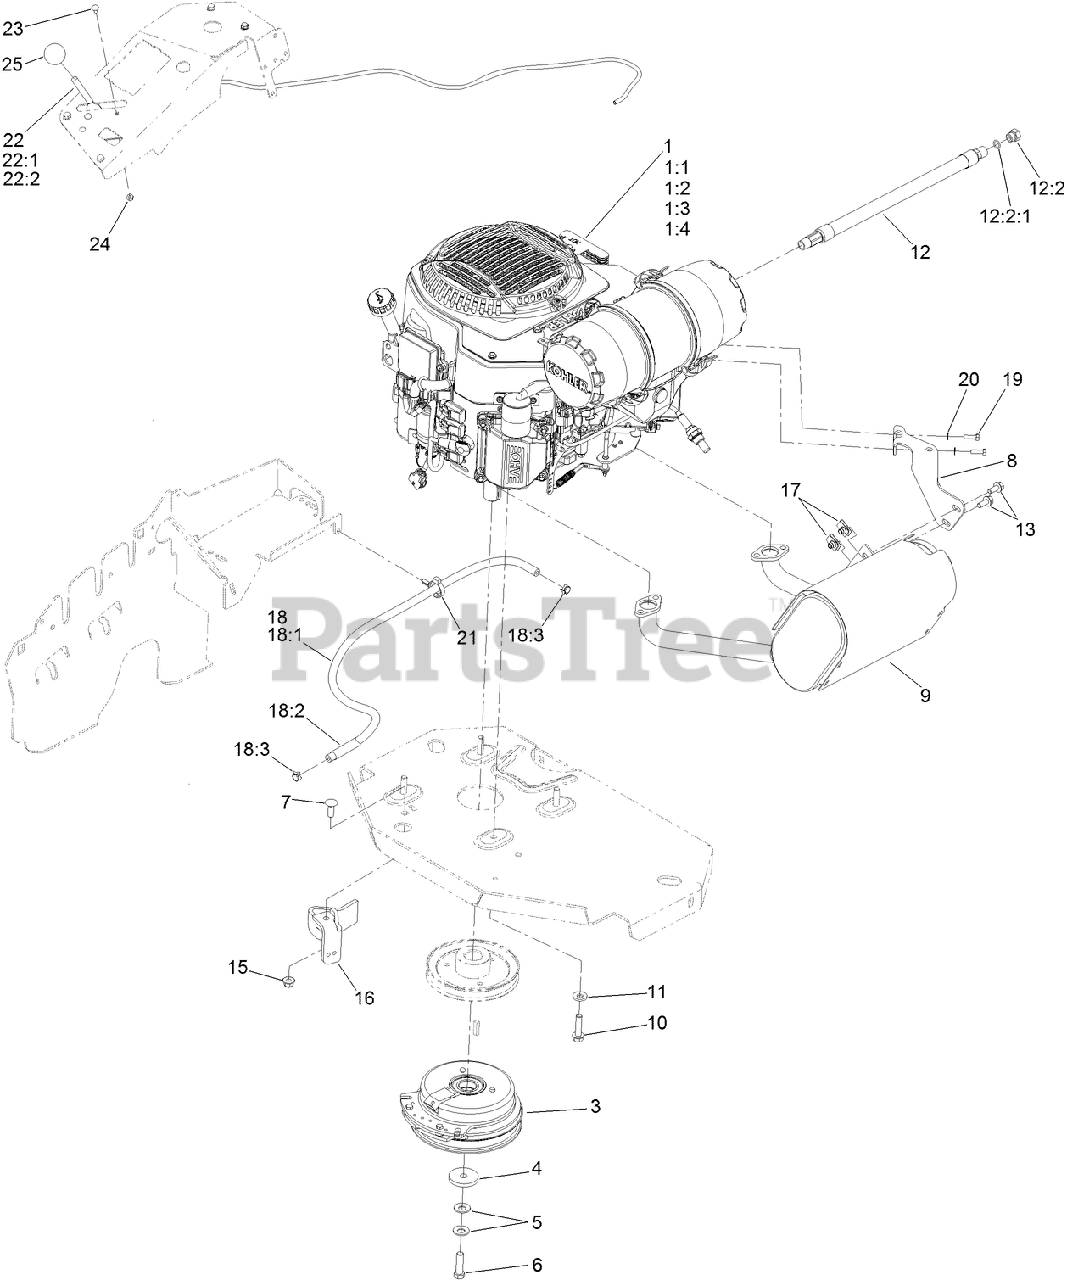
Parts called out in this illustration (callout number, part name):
1:1	KOHLER 52 050 02-S ENGINE OIL FILTER
1:2	KOHLER 25 083 01-S ENGINE AIR FILTER
1:3	KOHLER 25 083 04-S SAFETY FILTER
1:4	KOHLER 25 050 42-S FUEL FILTER
3	CLUTCH KIT
4	WASHER-CLUTCH
5	WASHER-SPRING
6	SCREW-HH, W/LOCTITE
7	SCREW-CARR
8	MUFFLER BRACKET KIT
9	MUFFLER KIT
10	SCREW-HWH
11	WASHER-BELLEVILLE
12	OIL DRAIN HOSE ASM
12:2	PLUG-HH
12:2:1	O-RING
13	SCREW-HH
15	NUT-HF, NI
16	CLUTCH-ANCHOR
17	NUT-U
18	FUEL LINE ASM
18:1	HOSE-FUEL
18:2	SLEEVE-THERMAL
18:3	CLAMP-HOSE
19	SCREW-HH
20	WASHER-SPRING
21	CLAMP-HOSE
22	THROTTLE CONTROL ASM
22:1	LEVER-THROTTLE
23	BOLT-CARR
24	NUT-LOCK, NI
25	KNOB-BALL
